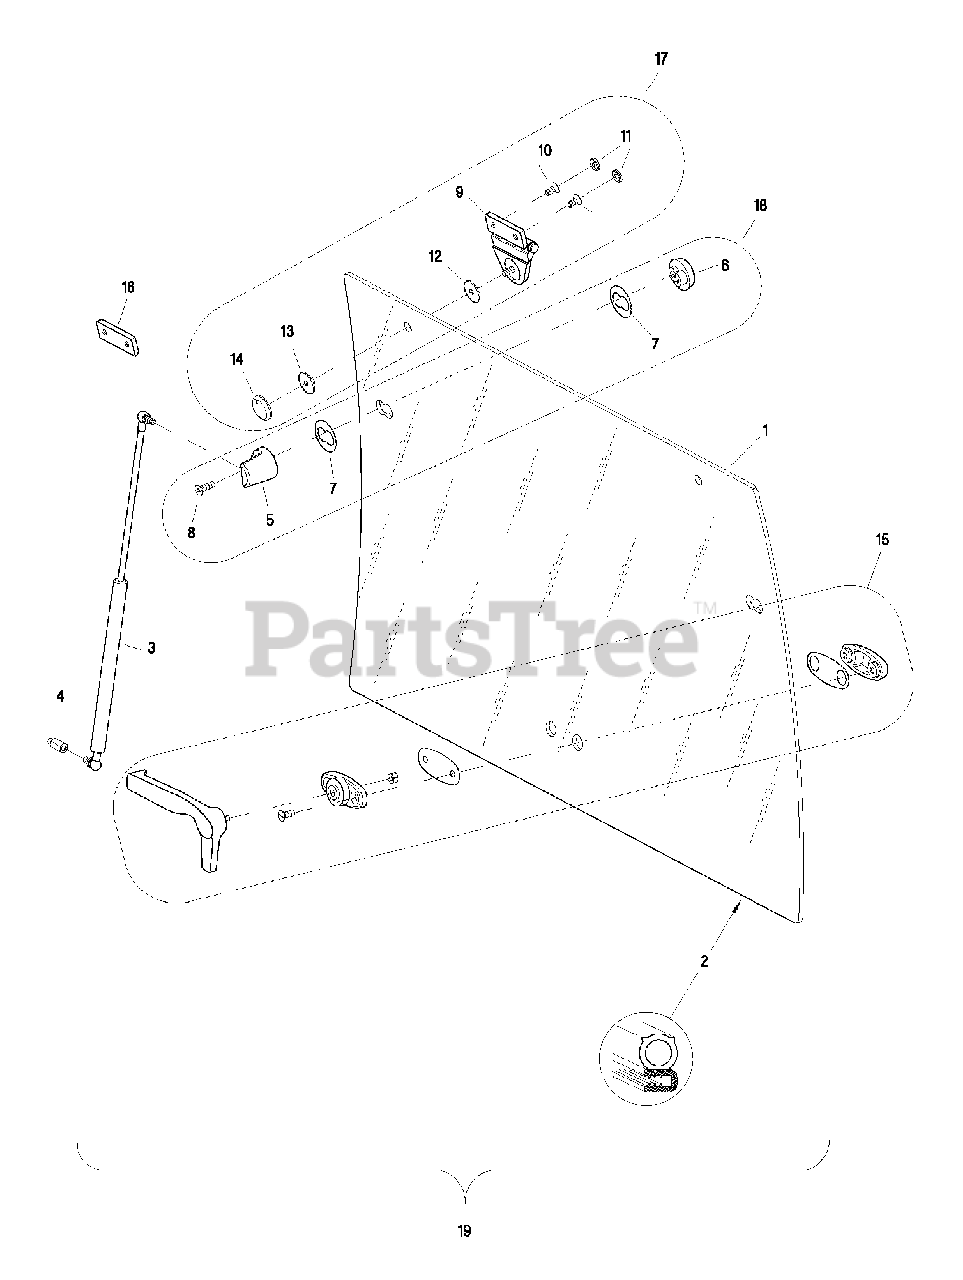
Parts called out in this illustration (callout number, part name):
1	WINDOW, Rear
2	PROFILE SEALING, 10 ft.
3	GASLIFT, 500MM/200N
4	SOCKET, GASLIFT
5	BEARING, Inner Gaslift
6	BEARING, Outer Gaslift
7	WASHER, Rubber
11	SCREW, Cover
12	WASHER, Rubber
13	WASHER, Rubber with Socket
14	WASHER, with Bushing, M8
15	HANDLE, Right Complete
15	HANDLE, Left Complete
16	INNER BRACKET, for Hinge
17	SET HINGE, (Includes Ref. 15 - 20)
18	SET GASSPRING SOCKET, (Includes Ref. 9 - 12)
19	WINDOW, Rear Complete, (Includes Ref. 2 - 20)
